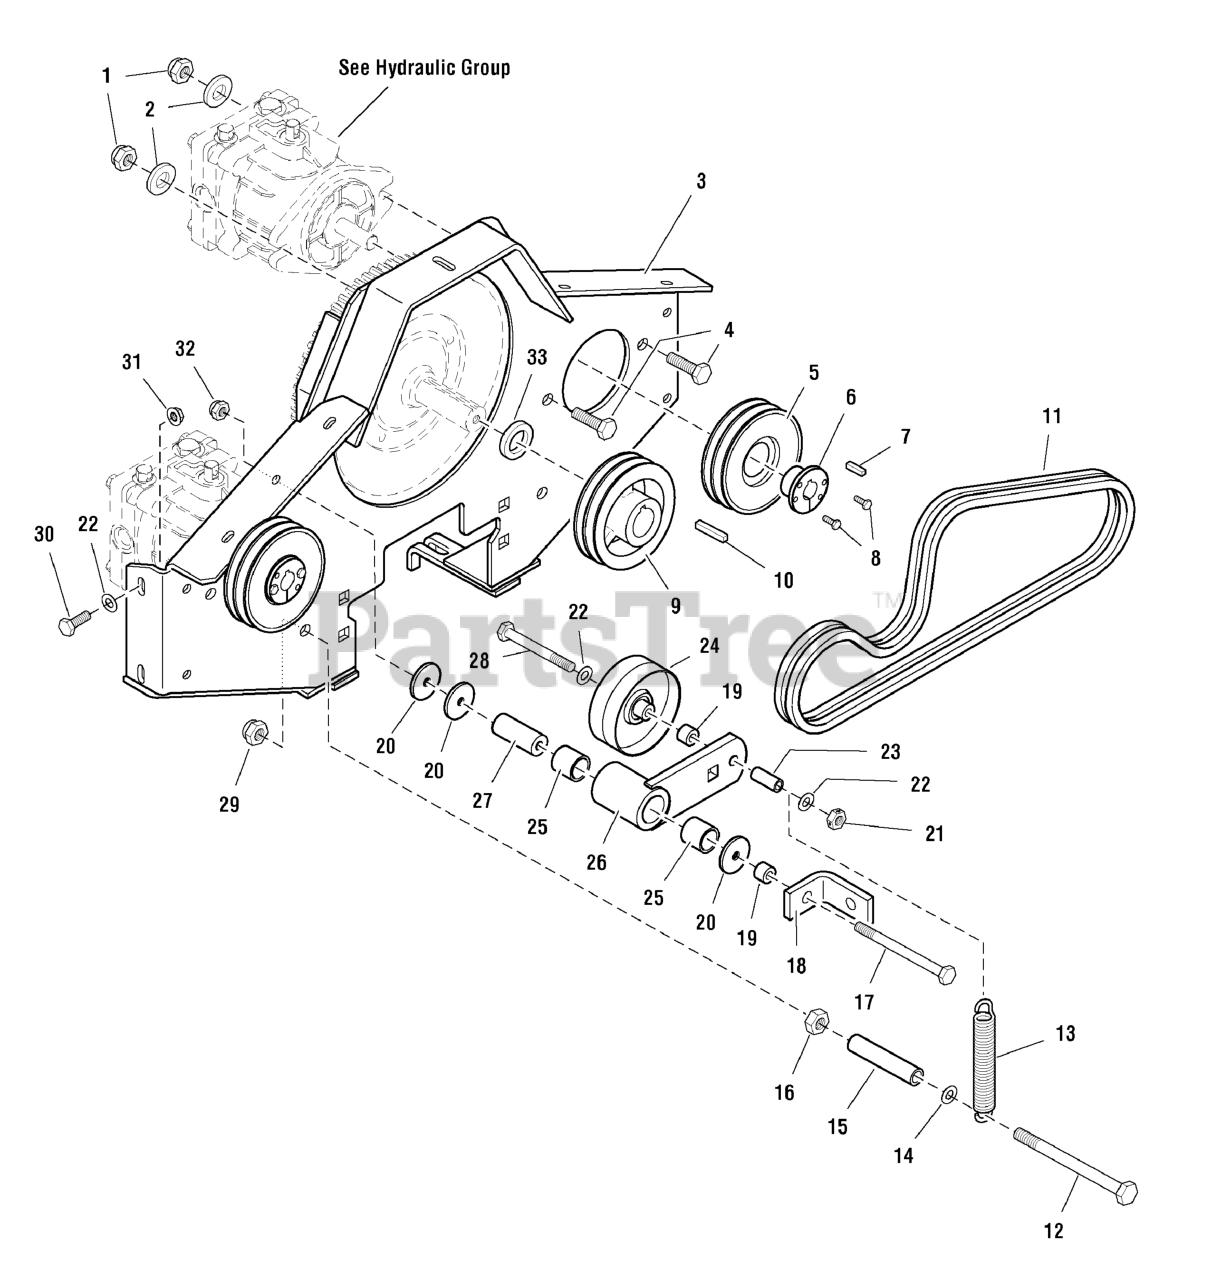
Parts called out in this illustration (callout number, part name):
1	NUT, Hex, Nylon Lock, 1/2-20
2	WASHER, Frame Retaining
3	PUMP MOUNT PLATE
4	BOLT, 1/2-20 X 1-3/4" GD8 CZ
5	PULLEY, Pump Drive
6	HUB, Taper Lock
7	KEY, 5MM SQ. x 25MM w/ Round Ends
8	BOLT, 1/4-20 X 1" GD5 CZ
9	PULLEY, Pump Drive
10	KEY, 1/4 SQ. X 3
11	BELT, Pump Drive (set of 2)
12	BOLT, 1/2-13 x 5
13	SPRING, Extension, Swivel End
14	WASHER, 1/2 SAE
15	HOSE, 3-1/4
16	NUT, 1/2-13 Hex Jam
17	BOLT, 3/8-16 X 4-1/2" GD5 CZ
18	SPRING ANCHOR
19	SPACER, .39 x .75 x .38
20	WASHER, 3/8 x 1-3/4
21	NUT, 3/8-16 Hex Side Lock
22	WASHER, 3/8 SAE
23	SPACER, .38 x .50 x .75
24	PULLEY, Idler, Flat
25	BUSHING, Brass
26	PUMP DRIVE IDLER ARM
27	SPACER, .39 X 1.00 X 2.55, SS
28	BOLT, 3/8-16 X 3" GD5 CZ
29	NUT, 1/2-13 HEX NYLON LOCK
30	BOLT, 3/8-16 X 1" GD5 CZ
31	NUT, 3/8-16 Hex Serrated Flange
32	NUT, 3/8-16 HEX NYLON LOCK
33	SPACER, 1.13 x 1.75 x .25
